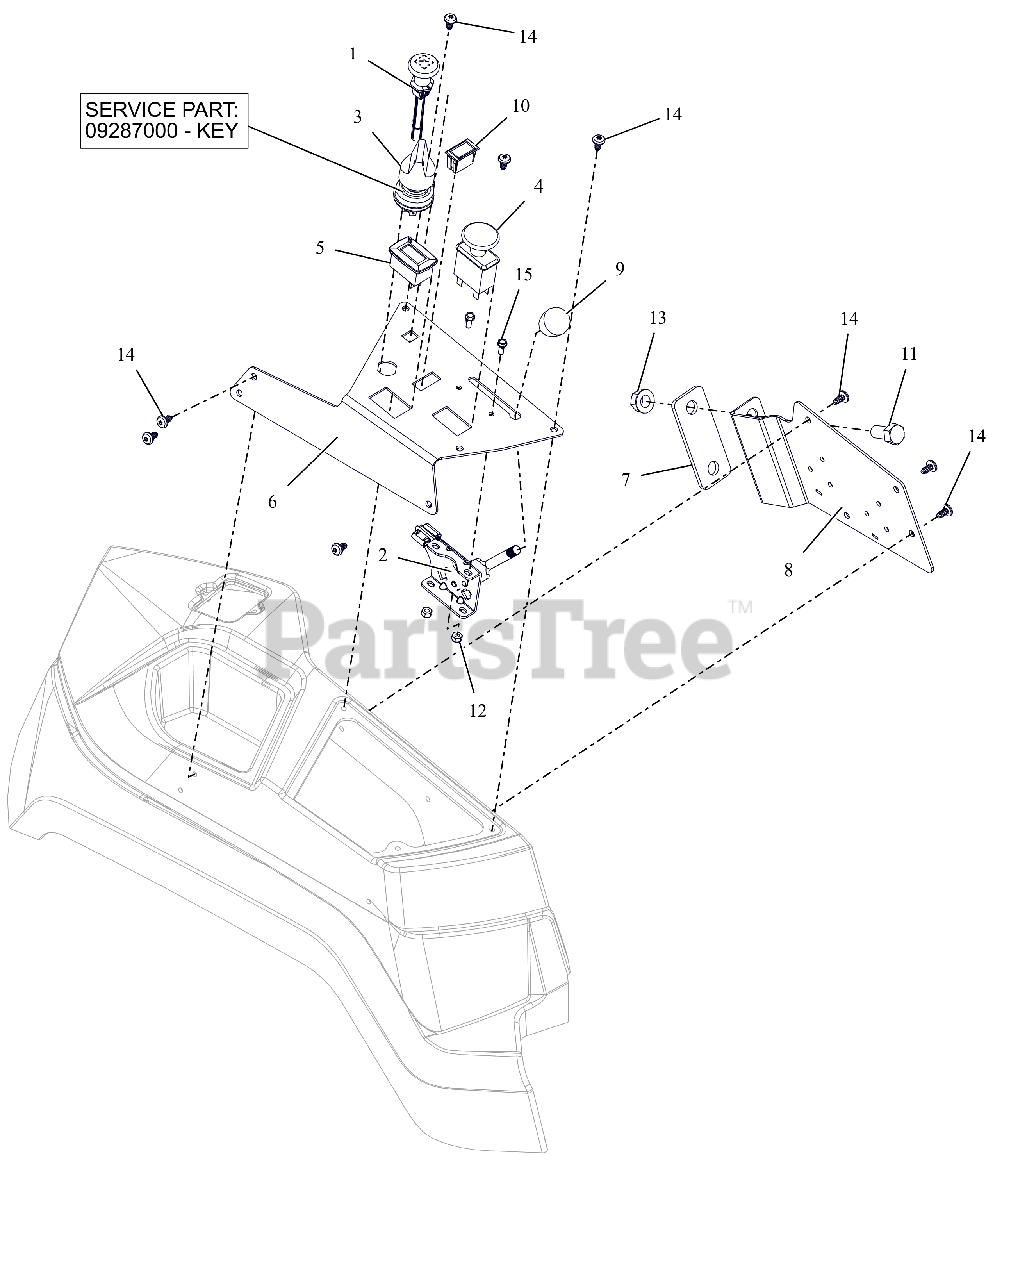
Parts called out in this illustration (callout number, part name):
1	CABLE - CHOKE, SNAP-IN
2	CABLE, PRO THROTTLE CONTROL
3	SWITCH, IGNITION
3	KEY, W/ SHIELD
4	SWITCH, CLUTCH
5	METER, HOUR W/MAINTENANCE
6	PLATE, APEX CONTROL PANEL
7	PLATE, CONTROL PANEL SPACER
8	BRKT, FENDER/RELAY MOUNTING
9	KNOB-CONTROL-BLACK .38-16X.50
10	SWITCH,BLANK
11	BLT, HEX .50-13X1.00 G5 ZCC
12	NUT-LK-NYL #10-24 G2 ZCC
13	NUT-LK-TOP-FLG .500-13 GF ZCC
14	SCR-PAN .25-15X.50 6L H/LZB500
15	@SCR-MCH 10-24X.50 HWH YWZC
